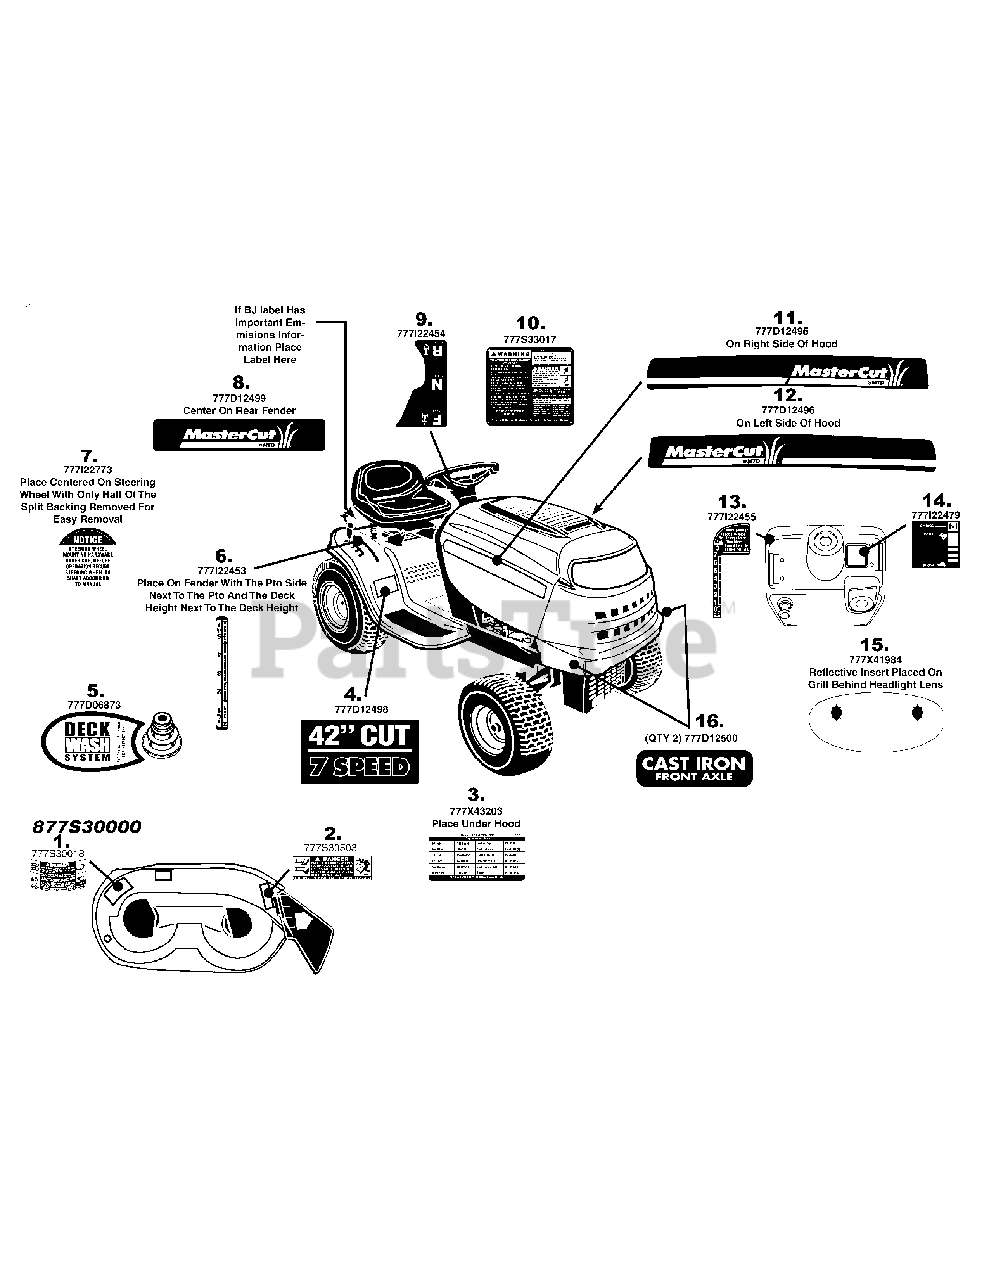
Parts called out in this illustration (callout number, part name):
1	LABEL-DECK SAFETY
2	LABEL-DANGER CHUTE
3	LABEL-RIDER PARTS LIST J775G059
4	LABEL-RIDER 42" CUT 7 SPD
5	LABEL-DECK
6	LABEL:RIDER LT-5 FENDER
7	LABEL-RIDER:SECURE WHEEL
8	LABEL-RIDER RH FENDER MASTERCUT
9	LABEL:RIDER LT-5 FENDER
10	LABEL-LT 5 TRANS COVER NO OCR
11	LABEL-RIDER HOOD RH MASTERCUT
12	LABEL-RIDER HOOD LH MASTERCUT
13	LABEL:RIDER LT-5 DASH
14	LABEL: RIDER LT-5 THRT/CHK
15	LABEL:RIDER 1&5 STYLE GRILL
16	LABEL-RIDER LOWER HOOD CAST IRON
